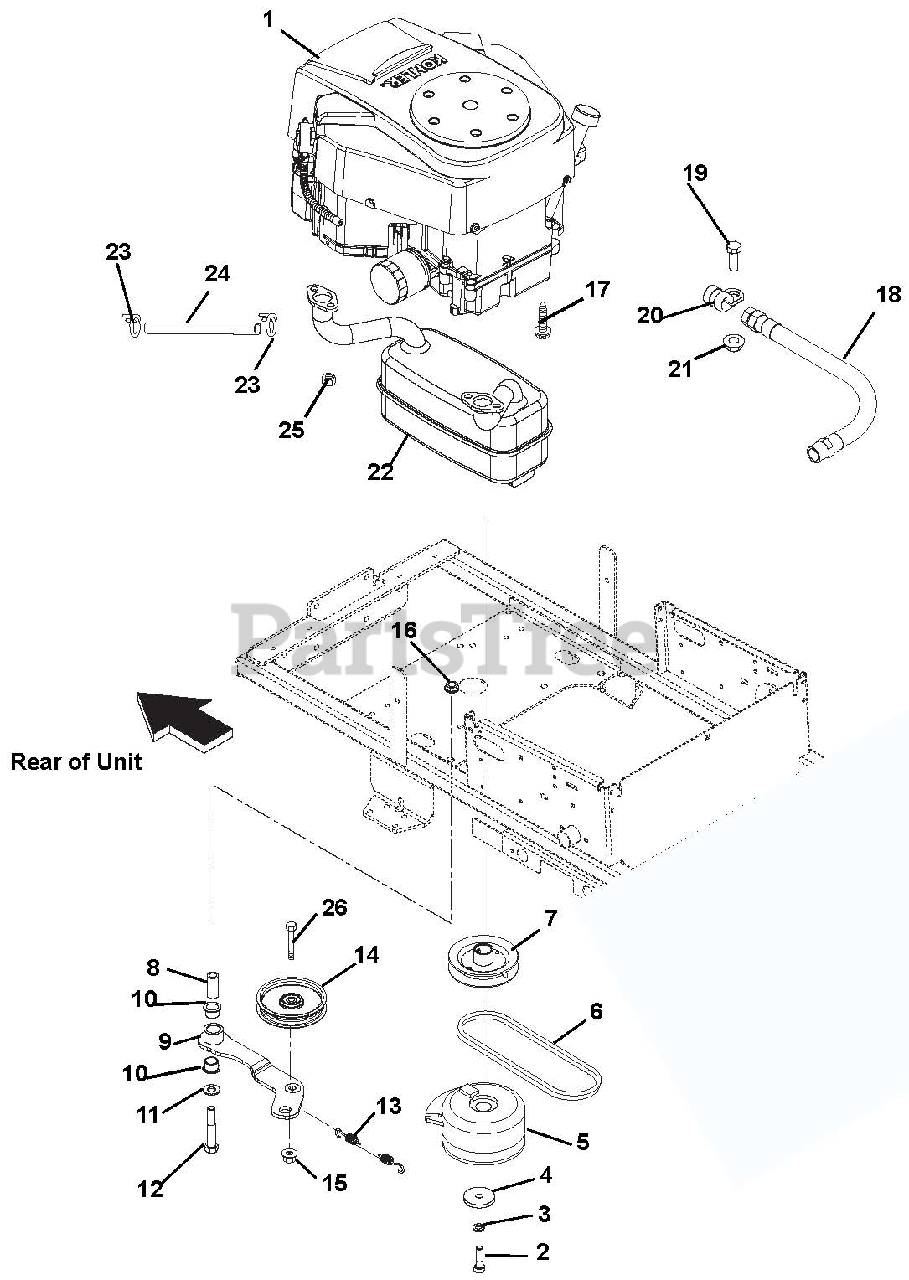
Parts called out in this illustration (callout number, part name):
1	ENGINE, 22 KOLHER COURAGE
2	7/16-20X3 HHCS GR8 YWZC
3	@WSHR-LK .44X.109 REG YWZC
4	WSHR-FL-STL .469X2.00X.25 YWZC
5	CLUTCH, ELECTRIC
6	V-BELT, HA-WRAPPED
7	SHEAVE, GROUND DRIVE
8	BSHG-SLV .500X.750X1.560
9	WMT, IDLER
10	BSHG-FLG 0.75X0.875X.625X1.125
11	@WSHR-FL-STL.531X1.06X.095YWZC
12	@BLT-HEX .50-13X3.25 GR5 YWZC
13	SPRING, EXT
14	IDLER-FLAT 4.00 X .38 NWHAMSHR
15	@NUT-LK-NYL-FLG .38-16 YWZC
16	@NUT-LK-TOP-FLG .50-13 YWZC
17	@SCR-TAP .38-16X1.00 HWH TR YZ
18	HOSE, HYD .38-11-0K M6N0-F6J0
19	@BLT-HEX .31-18X.75 GR5 YWZC
20	CLAMP, CUSHIONED STEEL .75
21	@NUT-LK-NYL-FLG .31-18 YWZC
22	MUFFLER, WMT (COURAGE)
23	CLAMP-HOSE WIRE .490/.510X.116
24	GAS LINE-BULK 1/4" I.D.
25	NUT, TOP LOCK FLG 8X1.25 YWZC
26	@BLT-HEX .38-16X2.00 GR5 YWZC
